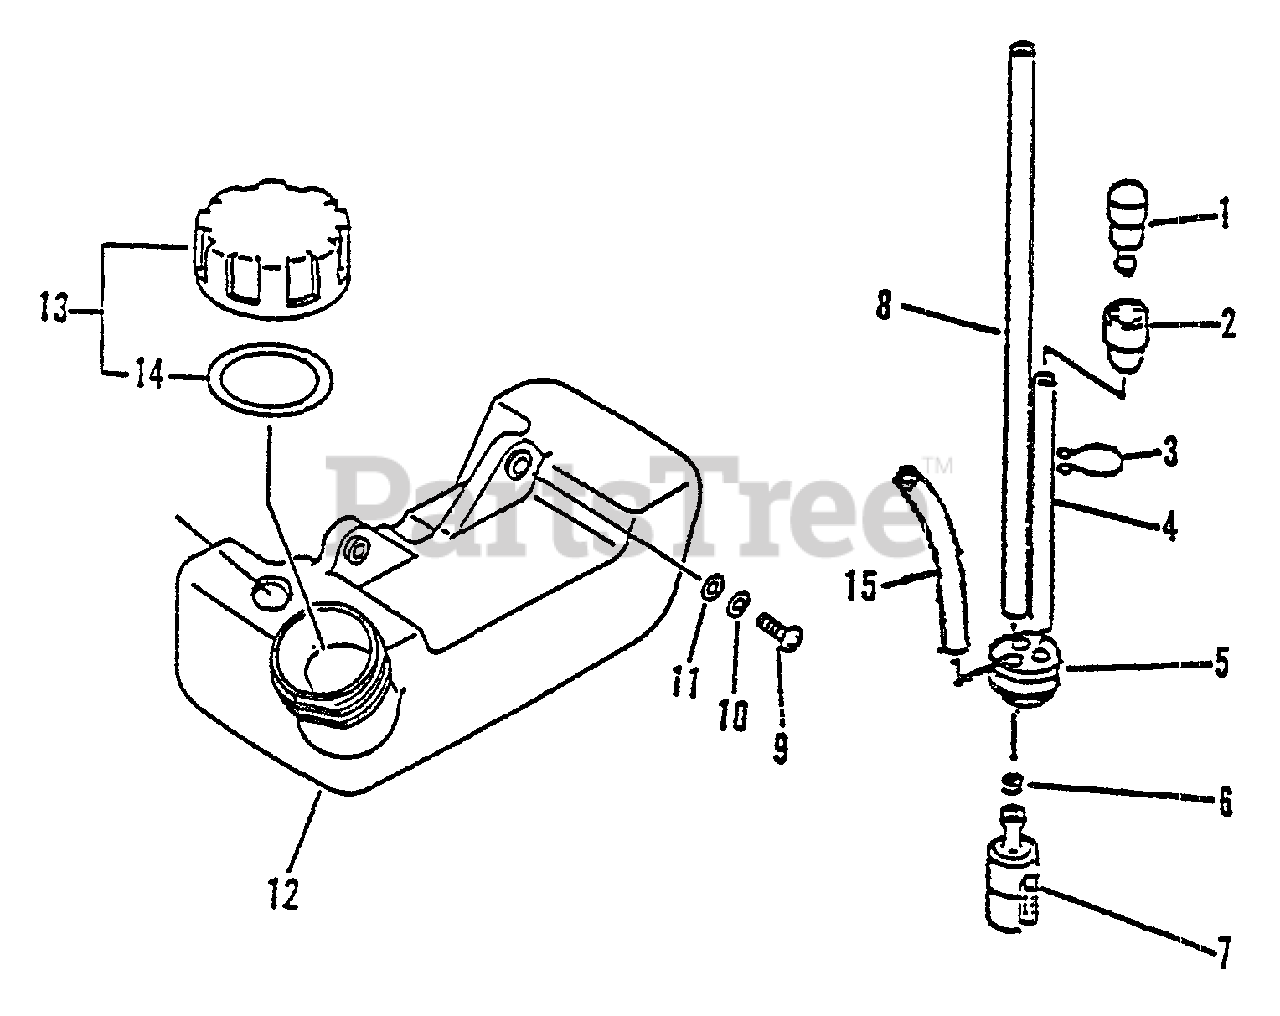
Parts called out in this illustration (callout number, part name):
1	VENT, FUEL TANK
2	COVER, VENT
4	PIPE - 3X5X70 -- BLACK
5	GROMMET
6	CLIP - 6
7	FILTER, FUEL
8	PIPE - 3X5X180 -- BLACK
9	SCREW - 5X16
10	LOCKWASHER - 5
11	WASHER - 5
12	TANK, FUEL
13	CAP ASSY
14	GASKET, CAP
15	PIPE - 3X6X90 -- CLEAR
